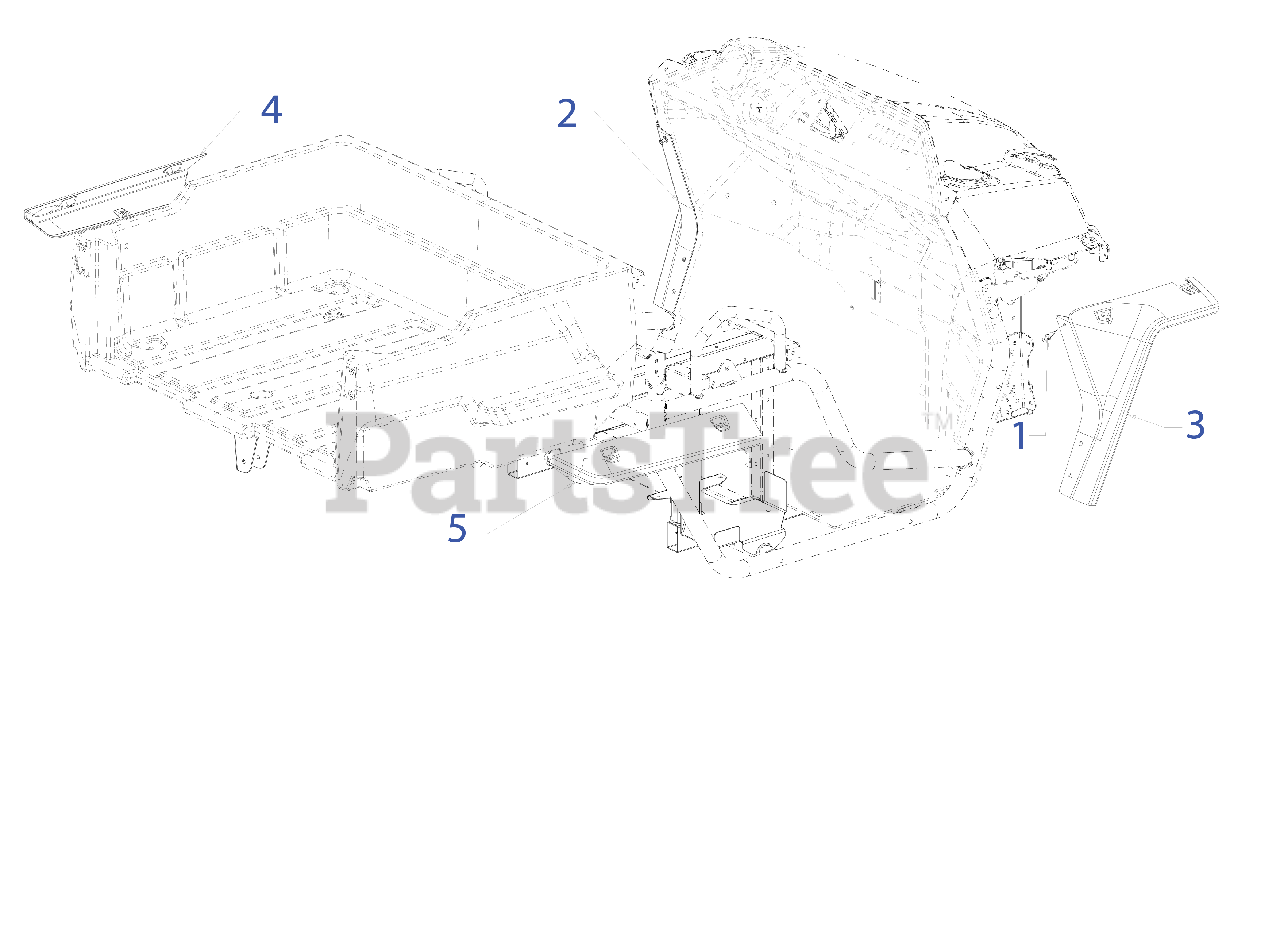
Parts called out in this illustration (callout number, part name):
1	PLASTIC RIVET
2	FRONT FENDER (LH) (YELLOW)
3	FRONT FENDER (RH) (YELLOW)
4	REAR FENDER (LH) (YELLOW)
5	REAR FENDER (RH) (YELLOW)
